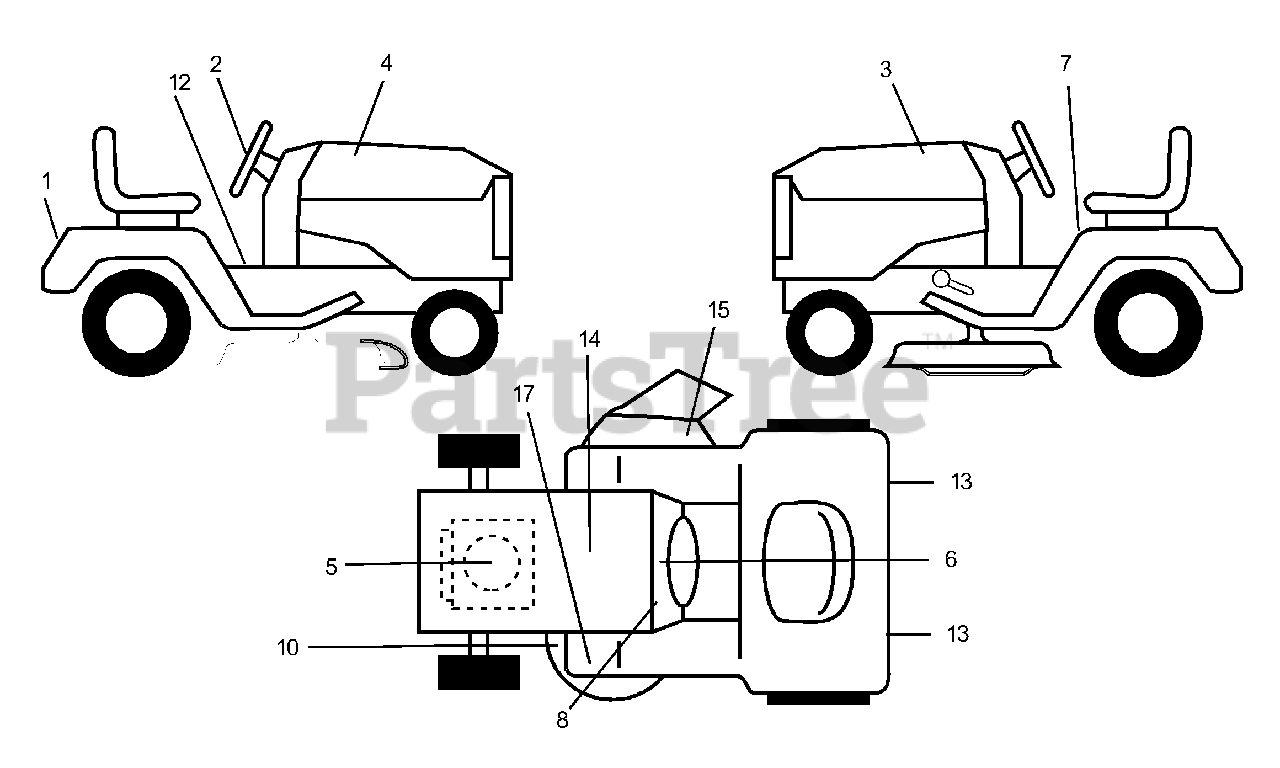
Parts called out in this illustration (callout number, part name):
1	Decal,Fender
2	Decal Wheel Steering
3	Decal, Hood LH
4	Decal, Hood RH
5	Decal, HP Engine
6	Decal Logo Dash
7	Decal, Danger Fender English/French
10	Decal, V-Belt Sch
12	Decal, Saddle Oper Instr.
13	Reflector Taillight
14	Decal, Btry Dngr/Psn
15	Decal, Warning Multi-Language
17	Decal, Clutch/Brake
